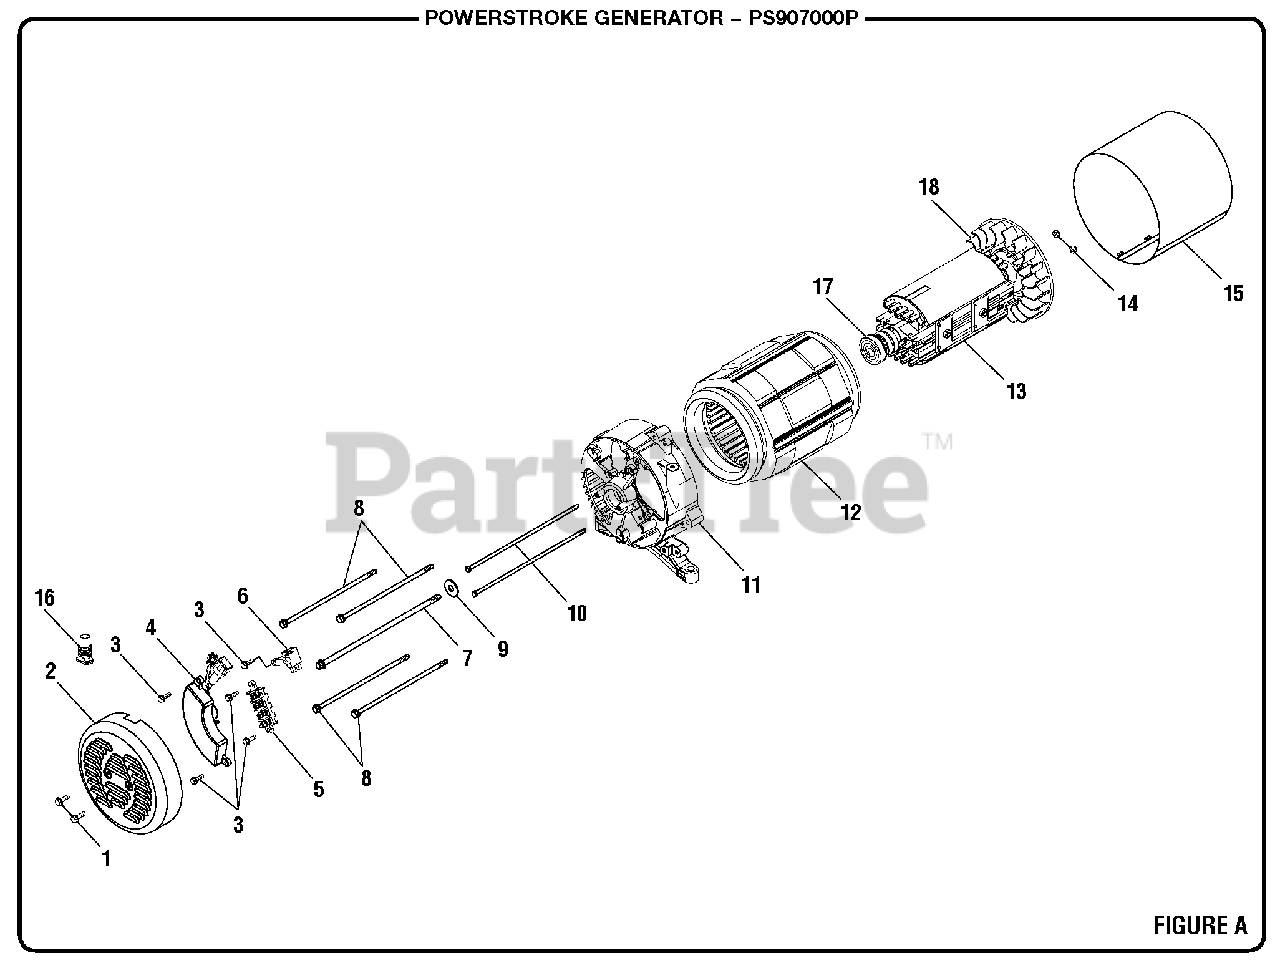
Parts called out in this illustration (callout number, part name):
1	Bolt (M5 x 12 mm, Hex Flange Hd.)
2	Brush Cover
3	Bolt (M5 x 16 mm, Hex Flange Hd.)
4	Automatic Voltage Regulator (5000 Watt)
5	Terminal Block
6	Brush Assembly 190 mm
7	Rotor Bolt (170 mm)
8	Bolt (M5 x 170 mm, Hex Washer Hd.)
9	Washer (ID10.5 x OD25 x 2t)
10	Bolt (M5 x 170 mm, Hex Washer Hd.)
11	Bearing Housing'
14	Hex Nut (M5)
15	Generator Head Cover
16	Rubber Boot
17	Ball Bearing (190 mm)
18	Fan (190 mm)
